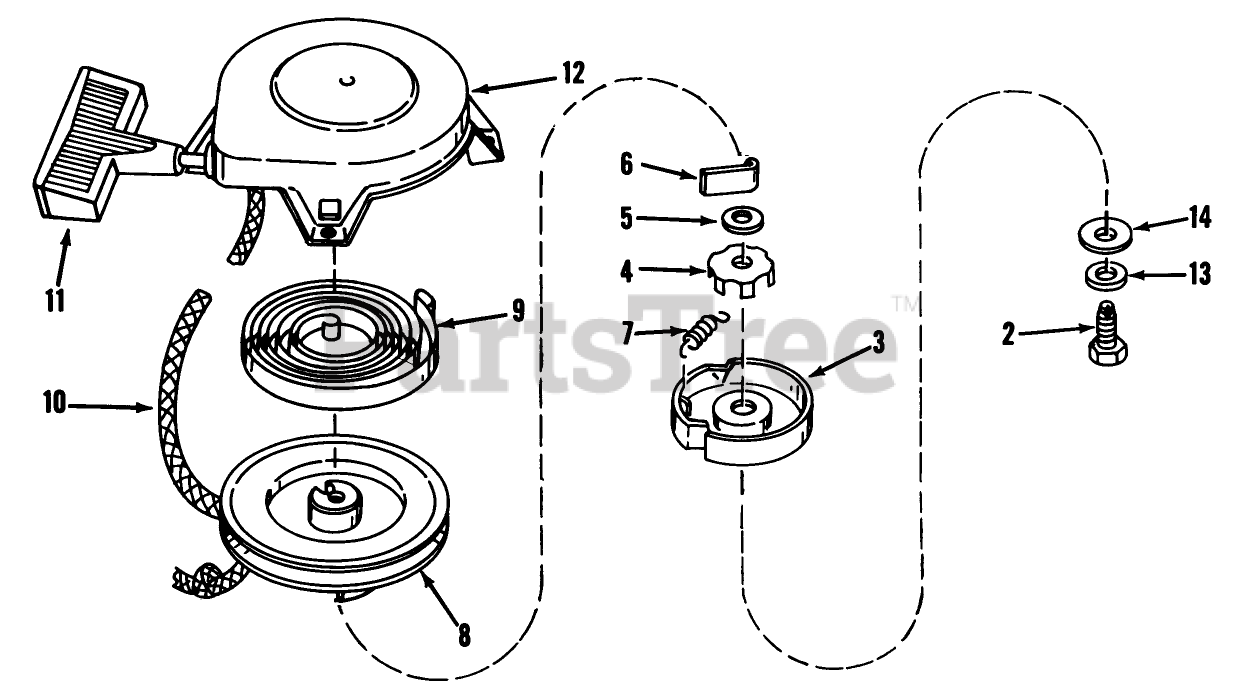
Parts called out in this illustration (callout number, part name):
2	Screw
3	Retainer
4	Brake
5	Washer, Thrust
6	Dog-Starter
7	Spring, Retainer
8	Pulley Assembly
9	Spring, Rewind
12	Housing, Starter
13	Washer, Brake
14	Washer, Spacer
